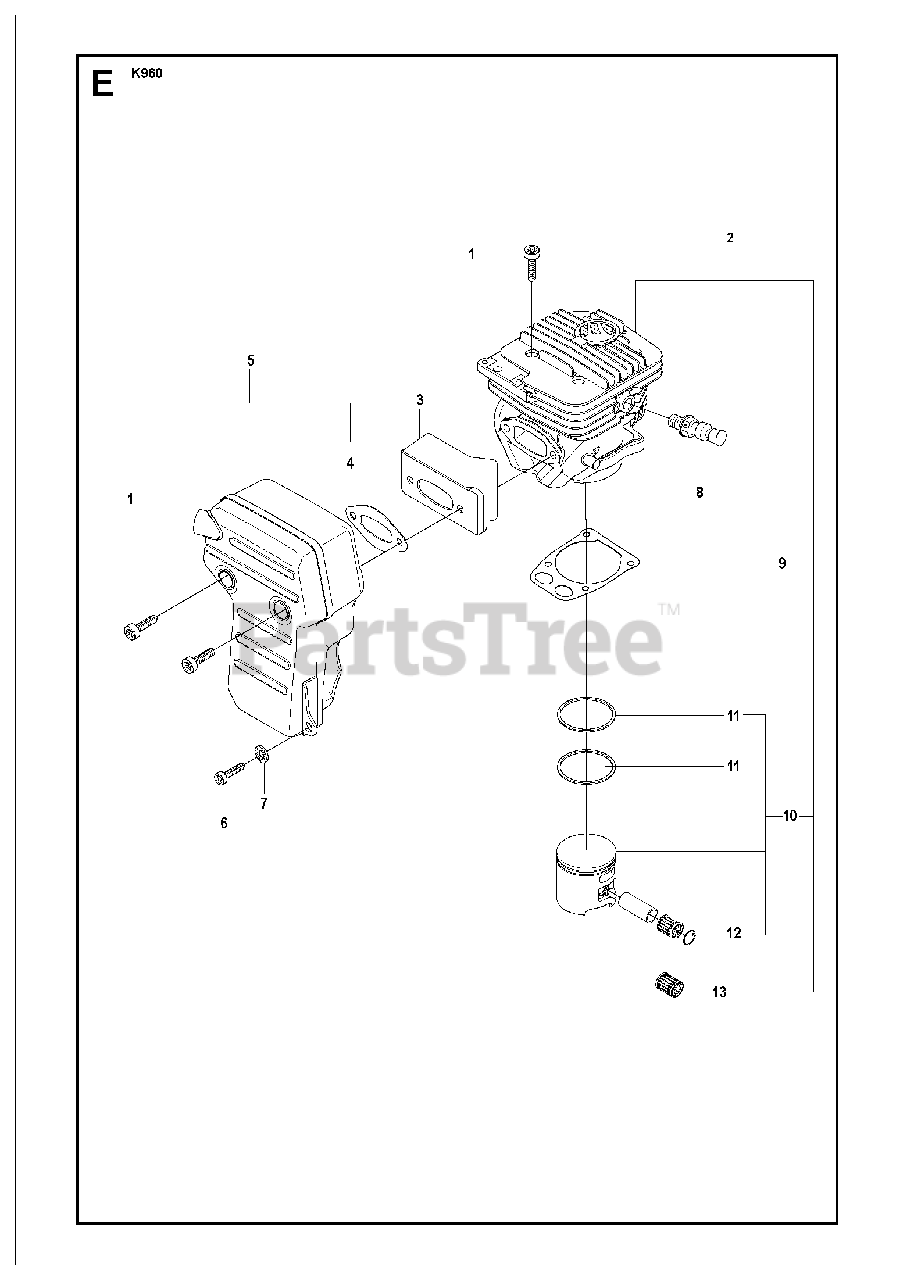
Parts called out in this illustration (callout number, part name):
1	SCREW ITXSCM
2	CYLINDER ASSYIncl. 9, 10, 13
4	GASKET
5	MUFFLER ASSYIncl. 1, 4
6	SCREW ITXSCM
8	DECOMPRESSION VALVE
9	GASKET
10	PISTONIncl. 11, 12
13	NEEDLE BEARING
